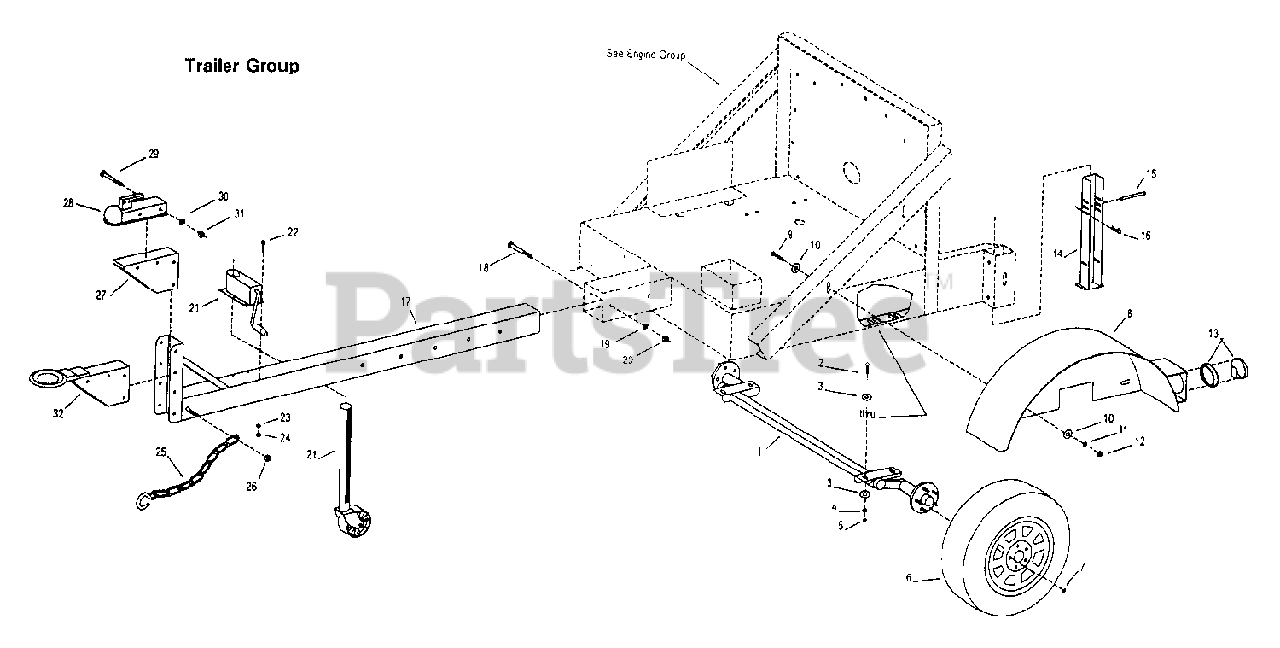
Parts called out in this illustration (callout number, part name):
1	Torflex Axle
2	1/2-13 x 1-1/4" Hex Bolt
3	1/2 Flat Washer
4	1/2 Lock Washer
5	1/2-13 Hex End Lock Nut
6	F78 x 15 Tire and Wheel Assembly
7	1/2-20 Lug Nut
8	Fender - Left Side
9	3/8-16 x 1" Hex Bolt
10	3/8 Flat Washer
11	3/8 Lock Washer
12	3/8-16 Hex Nut
13	Tail Lamp (w/Rubber Mounting Ring)
14	Support Leg
15	3/8 x 4" Clevis Pin
16	Bridge Pin
17	Draw Bar - Swing Jack Style
18	5/8 x 4-1/2" Hex Bolt
19	5/8 Split Lock Washer
20	5/8 Lock Nut
21	Jack, Trailer Support Swing Away Style
22	3/8-16 x 5" Hex Bolt
23	3/8 Split Lock Washer
24	Bridge Pin
25	Chain, Safety w/1 S-Hook
26	1/2-13 x 5" Hex Bolt
27	Ball Hitch Mount, Black
28	Ball Hitch
29	1/2-13 x 3-1/2" Hex Bolt
30	1/2 Lock Washer
31	1/2 Lock Nut
32	Pintle Ring (Optional)
